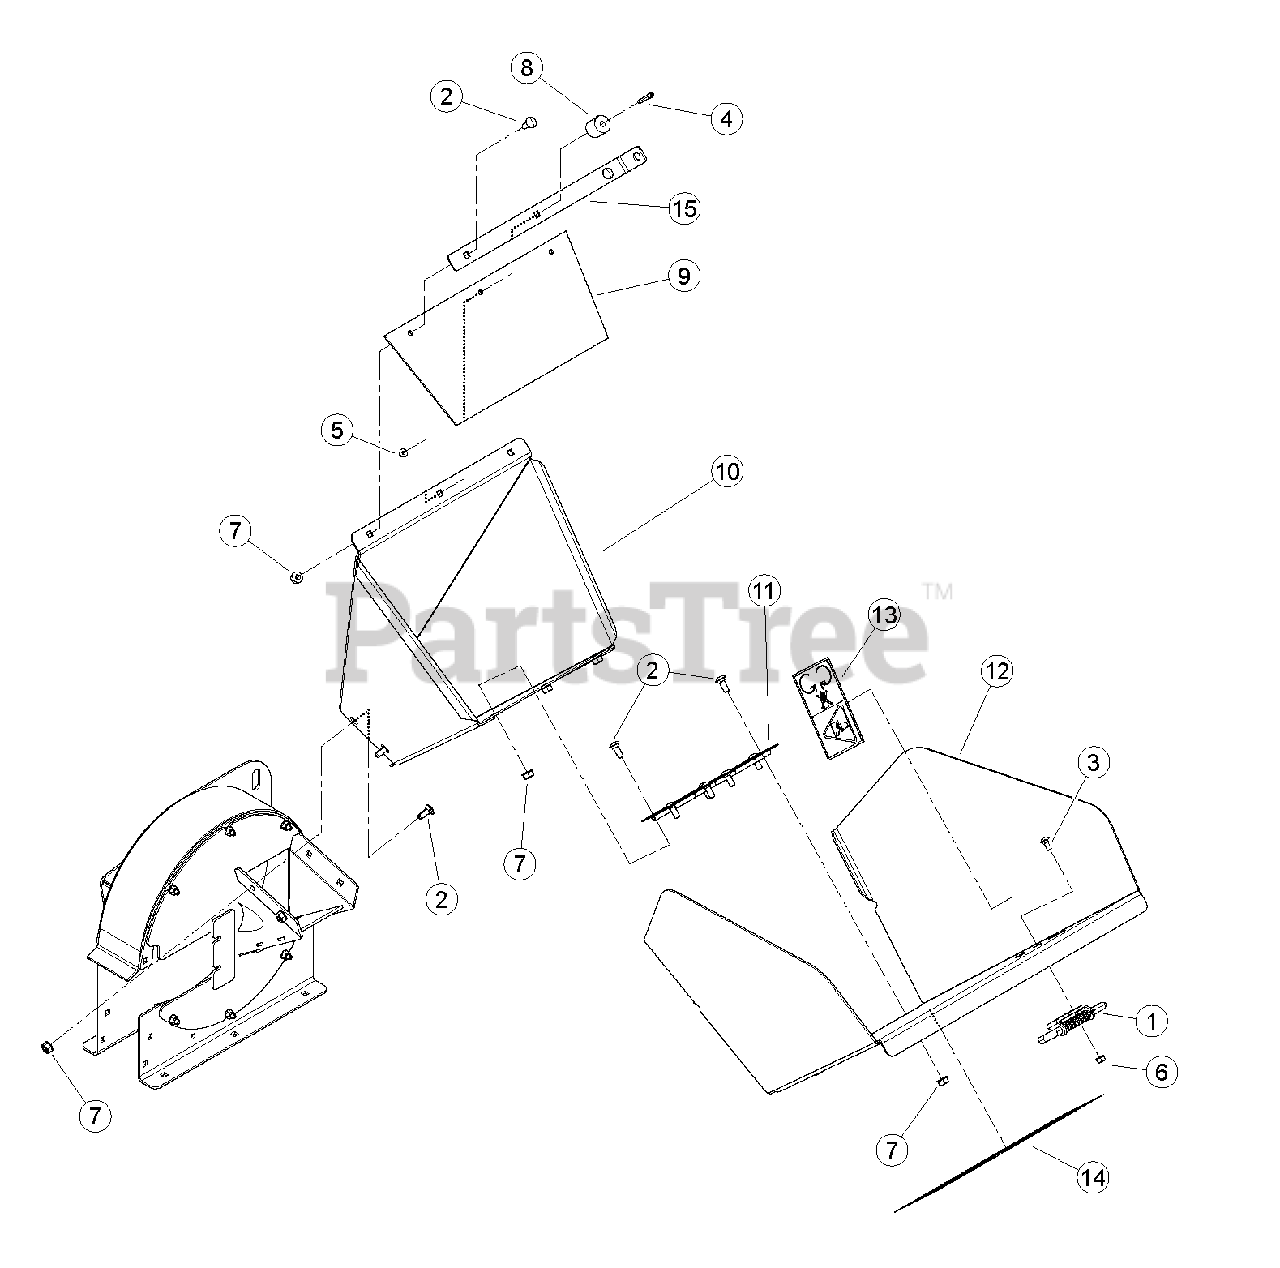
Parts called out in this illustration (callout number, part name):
1	LATCH, RH HINGE
2	BOLT, 3/8 X 1" CRG GR5 NC ZP
3	BOLT, 5/16 X 3/4 GR5 NC ZP CRG
4	SCREW, 1/4 X 1-1/2" SKT HD CAP
5	NUT, 1/4-20 NYLOCK-FLANGE
6	NUT, 5/16-18 NYLOCK-FLANGE
7	NUT, 3/8-16 NYLOCK-FLANGE
8	BUMPER, RECESSED RUBBER
9	FLAP, CHIPPER CHUTE
10	WELDMENT, HOPPER
11	HINGE, CHUTE EXTENSION
12	ASSEMBLY, 4-1/2" EXTENSION TRAY
13	DECAL, BLADE DANGER ISO
14	DECAL, BEARCAT WEB
15	STRIP, FLAP RETAINER
